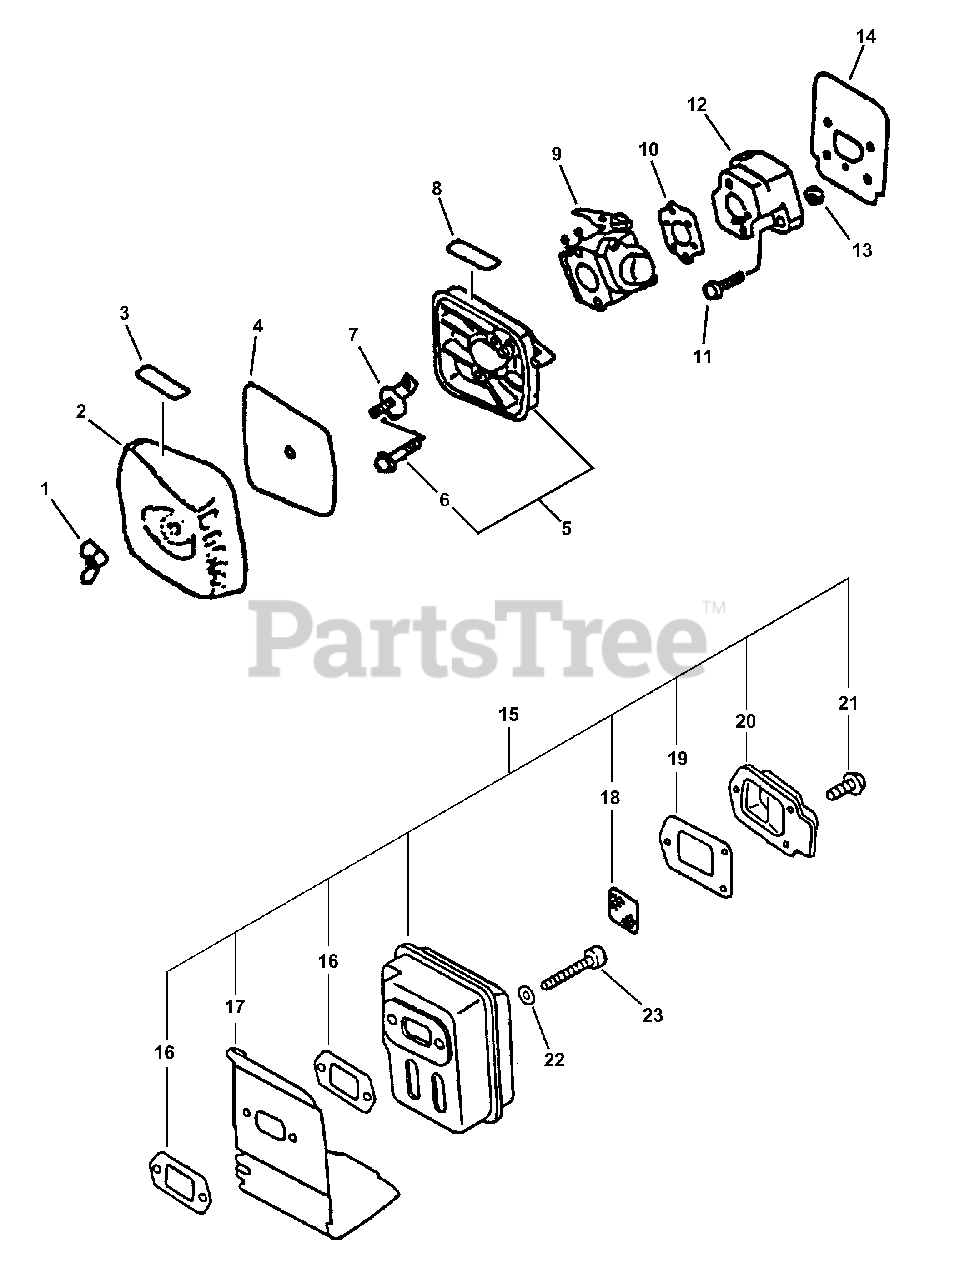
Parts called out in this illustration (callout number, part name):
1	WINGNUT - 6
2	COVER, AIR FILTER - GRAY
3	LABEL - TOP
4	FILTER, AIR - SINGLE LAYER
5	AIR FILTER CASE ASSY
6	SCREW - 5X65
7	PLATE, PREVENT
8	LABEL - CHOKE
9	CARBURETOR C1U-K16
9	CARBURETOR C1U-K47
9	CARBURETOR C1U-K52
10	GASKET, INTAKE
11	SCREW - 5X20
12	INSULATOR, INTAKE
14	SHIELD, INTAKE
15	MUFFLER ASSY
16	GASKET, EXHAUST
17	SHIELD, EXHAUST
18	SCREEN, SPARK ARRESTOR
19	GASKET, EXHAUST
20	GUIDE, EXHAUST - OUTER
21	SCREW - 4X10
22	WASHER - 5
23	SCREW - 5X55
